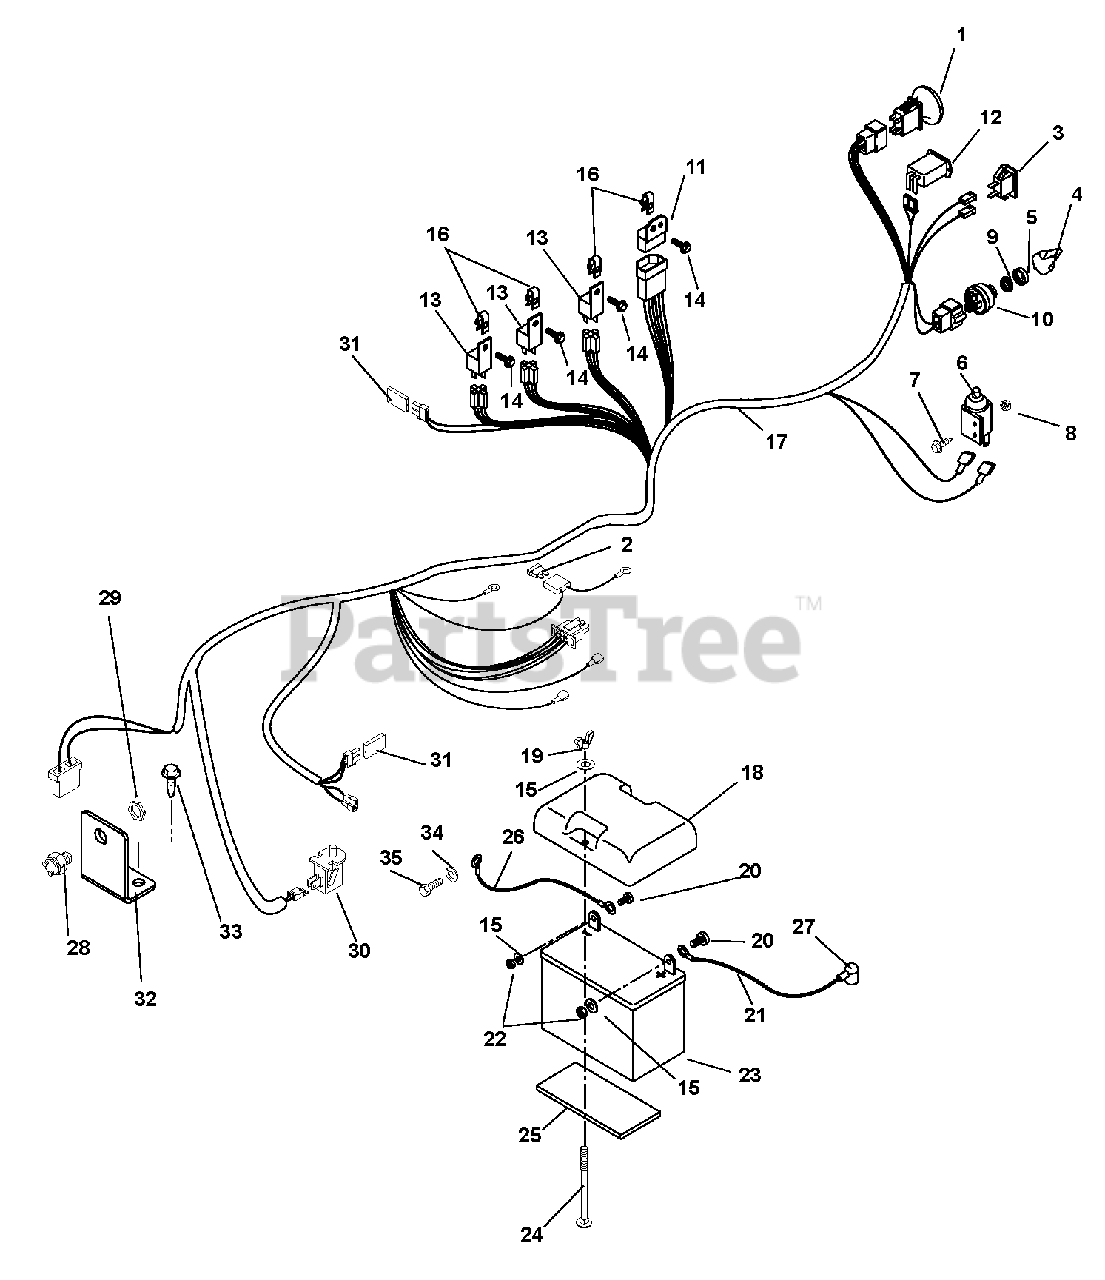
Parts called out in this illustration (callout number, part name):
2	Fuse, 30 Amp (Included with Harness)
3	Light, Indicator
4	Key with Shield
5	Cap, Ignition Switch
6	Switch, Single Pole (N.O.) with Cover
7	Screw, Machine 10-24 x .50 Hex Washer Head
8	Nut, Locking-Nylon 10-24 with Insert
9	Nut, Panel .562-24
10	Key Switch
11	Module, Time Delay
12	Hour Meter w/Maintenance
13	Relay (Included with Harness)
14	Screw, Machine 10-24 x .75 Hex Washer Head
15	Washer, Flat Steel .281 x .620 x .065
16	Retainer Nut 10-24
17	Harness, Wiring
18	Cover, Battery
19	Nut, Locking Wing .250-20
20	Bolt, Hex .25-20 x .75 Grade 5
21	Start Cable 22"
22	Nut, Locking Center .25-20
24	Bolt, Round Head Square Neck .25-20 x 7.50 Grade 2
25	Pad, Battery
26	Cable, Negative Battery 35" Long
27	Battery Terminal Boot, Red
28	Switch, Neutral Start (N.C.)
29	Nut, Stamped .56-18
30	Switch, Seat (Included with Seat)
31	Diode, Connector Shell (Included with Harness)
32	Bracket, Neutral Switch
33	Screw, Tapping .25-20 x .50
34	Washer, Locking .31 x .078 Regular
35	Bolt, Hex M8-1.25 x 20
